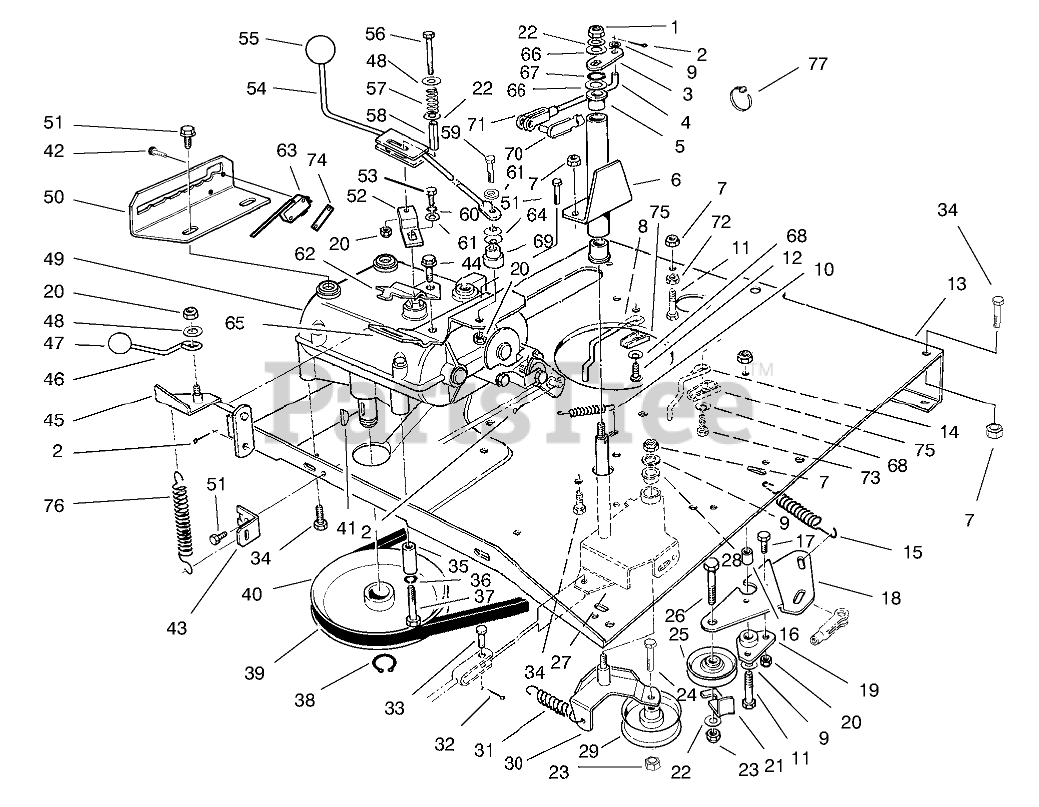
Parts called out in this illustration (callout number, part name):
1	NUT-LOCK, NI
2	PIN-COTTER
3	BRKT-DECK ENGAGE BLK
4	LINK-DECK ENGAGE
5	BUSHING-FLANGE
6	Tube W.A.-Pivot (Incl. Ref. #5)
7	NUT-LOCK, NI
8	ENG BELT GUIDE R.
9	WASHER-PLAIN
10	SPRING-RETURN, BRAKE
11	SCREW-HH
12	SCREW-HWHTF
13	PLATE-ENGINE
14	GUIDE-ENG. BELT L.
15	SPRING-TRACTION
16	SPACER-PIVOT
17	SCREW-HH
18	PLT-IDLER MTG
19	MOUNT-TRACTION PIVOT
20	NUT-LOCK, NI
21	RETAINER-BELT
22	WASHER-FLAT
23	NUT-LOCK, NI
24	SCREW-HH
25	PULLEY-IDLER
26	SCREW-HH
27	Bracket-Arm, Idler (Incl. Ref. #28)
28	BUSHING-FLANGE
29	PULLEY-IDLER
30	IDLER MTG PLT WA (BLACK)
31	SPRING-IDLER
32	PIN-COTTER
33	PIN-CLEVIS
34	SCREW-HH
35	GUIDE-BELT
36	WASHER-LOCK
37	SCREW-HH
38	RING-SNAP, EXTERNAL
39	67BELT, TRACTION DRIVE
40	PULLEY
41	KEY-WOODRUFF
42	SCREW-PHL 4-40X1 1/4
43	BRKT-SPRING MT
44	SCREW-HWHTF
45	DECK ENGAGE LEVER WA (BLACK)
46	ROD-ENGAGE
47	KNOB-CONTROL
48	WASHER-FLAT
49	TRANSMISSION
50	Gate-Shift
51	SCREW-HWHTF
52	LEVER-SHIFT
53	SCREW-HH
54	SHIFT LEVER WA (BLACK)
56	SCREW-HH
57	SPRING-COMPRESSION
58	SPACER-SPLIT
59	SCREW-HH
60	WASHER-LOCK
61	WASHER-FLAT
62	BRKT-DECK ENG UPPER
63	SWITCH-MICRO
64	WASHER-BELLEVILLE
65	BRKT-DECK ENG. SHIFTER
66	WASHER
67	RING-RETAINING
68	WASHER-BELLEVILLE
69	SPACER-PIVOT
70	CLEVIS PIN ASM
71	CLEVIS-ADJ
72	NUT-JAM
73	BOLT-CARR
74	NUT-SPEED
75	ANCHOR-GUIDE, BELT
76	SPRING-DOOR
77	TIE-CABLE
